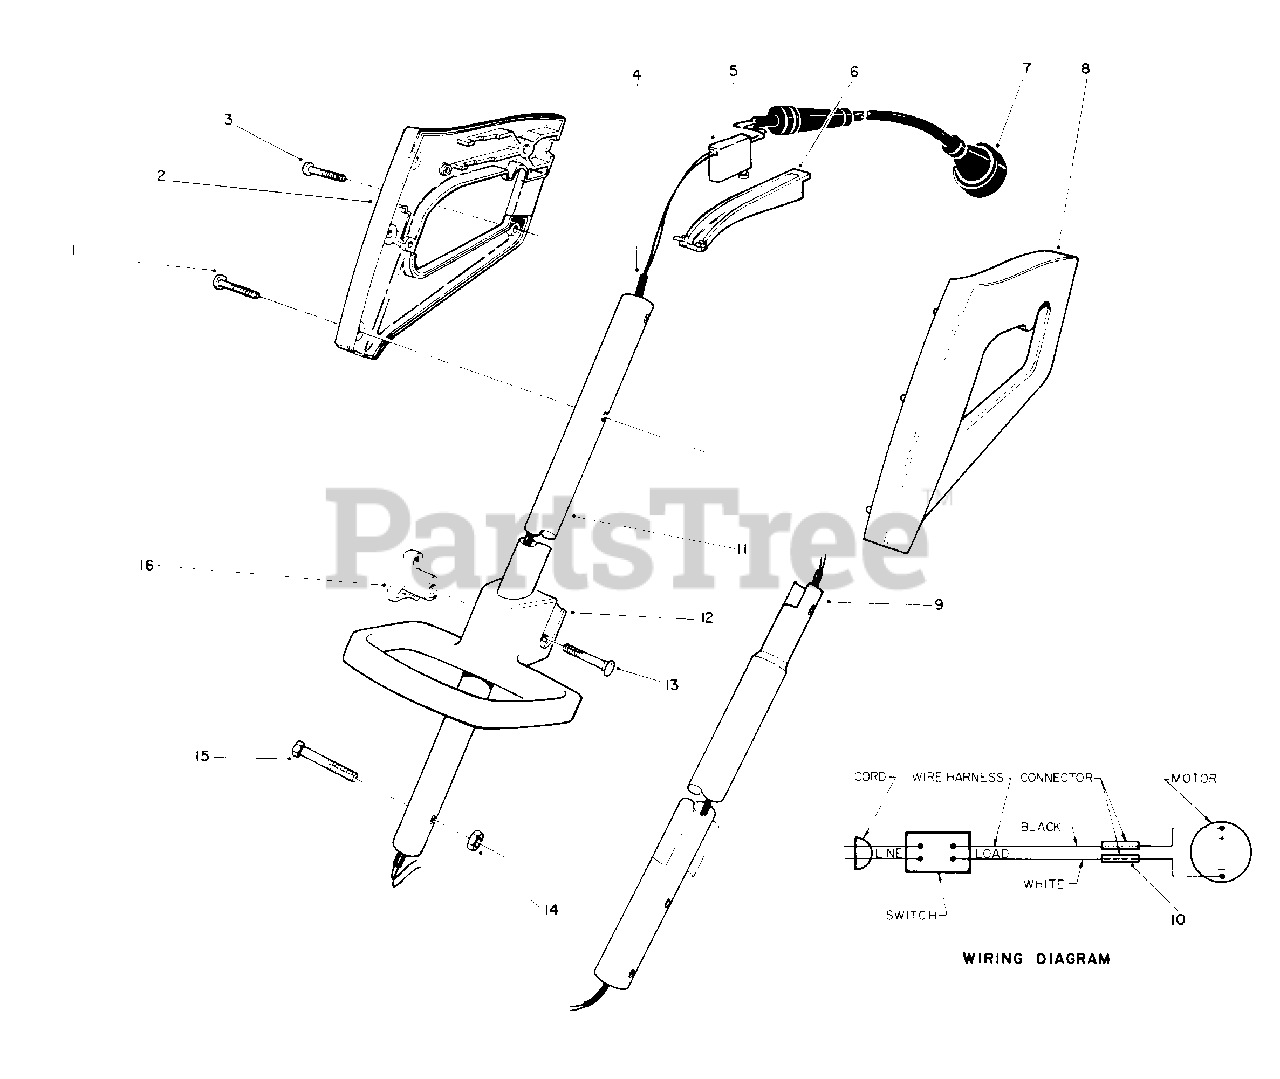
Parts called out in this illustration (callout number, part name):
1	Screw-Hex. Hd. Cap
2	Grip-Handle R.H.
3	Screw-Pan Hd.
4	Wire Harness Assembly
5	Switch
6	Bar-Switch
7	Cord-Power
8	Grip-Handle L.H.
9	Tube-Lower
10	Connector
11	Tube-Upper
12	Handle-Adjustable
13	Bolt-Carriage
14	Nut-Lock
15	Screw-Hex. Hd. Cap
16	Knob-Adjustment Handle
